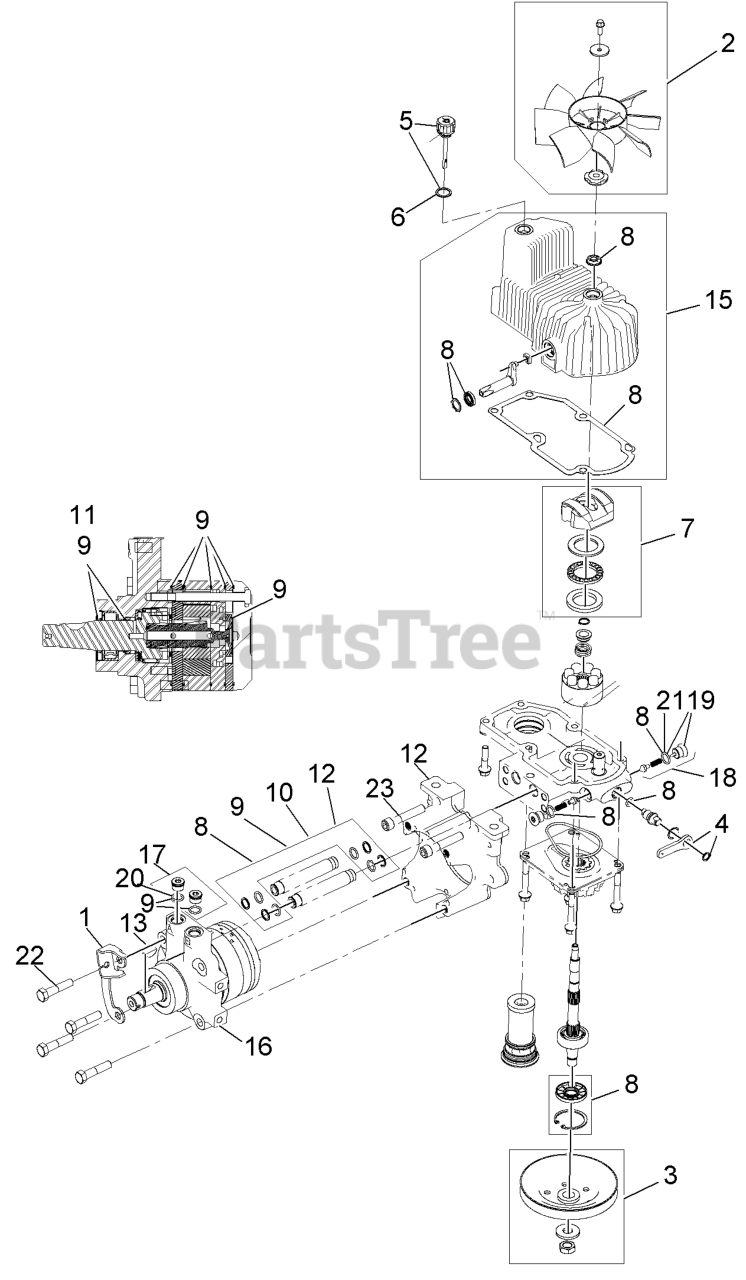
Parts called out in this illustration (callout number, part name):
1	BRACKET-ANCHOR, CABLE
2	FAN KIT
3	PULLEY KIT
4	HANDLE-BYPASS VALVE, HYDRO
5	DIPSTICK-HYDRO W/GASKET
6	GASKET-DIPSTICK, HYDRO
7	SWASH BLOCK KIT
8	PUMP SEAL KIT
9	MOTOR SEAL KIT
10	TUBE SEAL KIT
11	OUTPUT SHAFT SEAL KIT
12	NOSE CUP-UHT
13	KEY-WOODRUFF
15	HOUSING-HYDRO, RH
16	MOTOR-HYDRAULIC RH 240CC
17	MAGNETIC PLUGS SERVICE KIT
18	CHECK VALVE ASM
19	PLUG-CHECK (W/O-RING)
21	O-RING-CHECK VALVE
22	SCREW HH
23	SCREW-HSH
